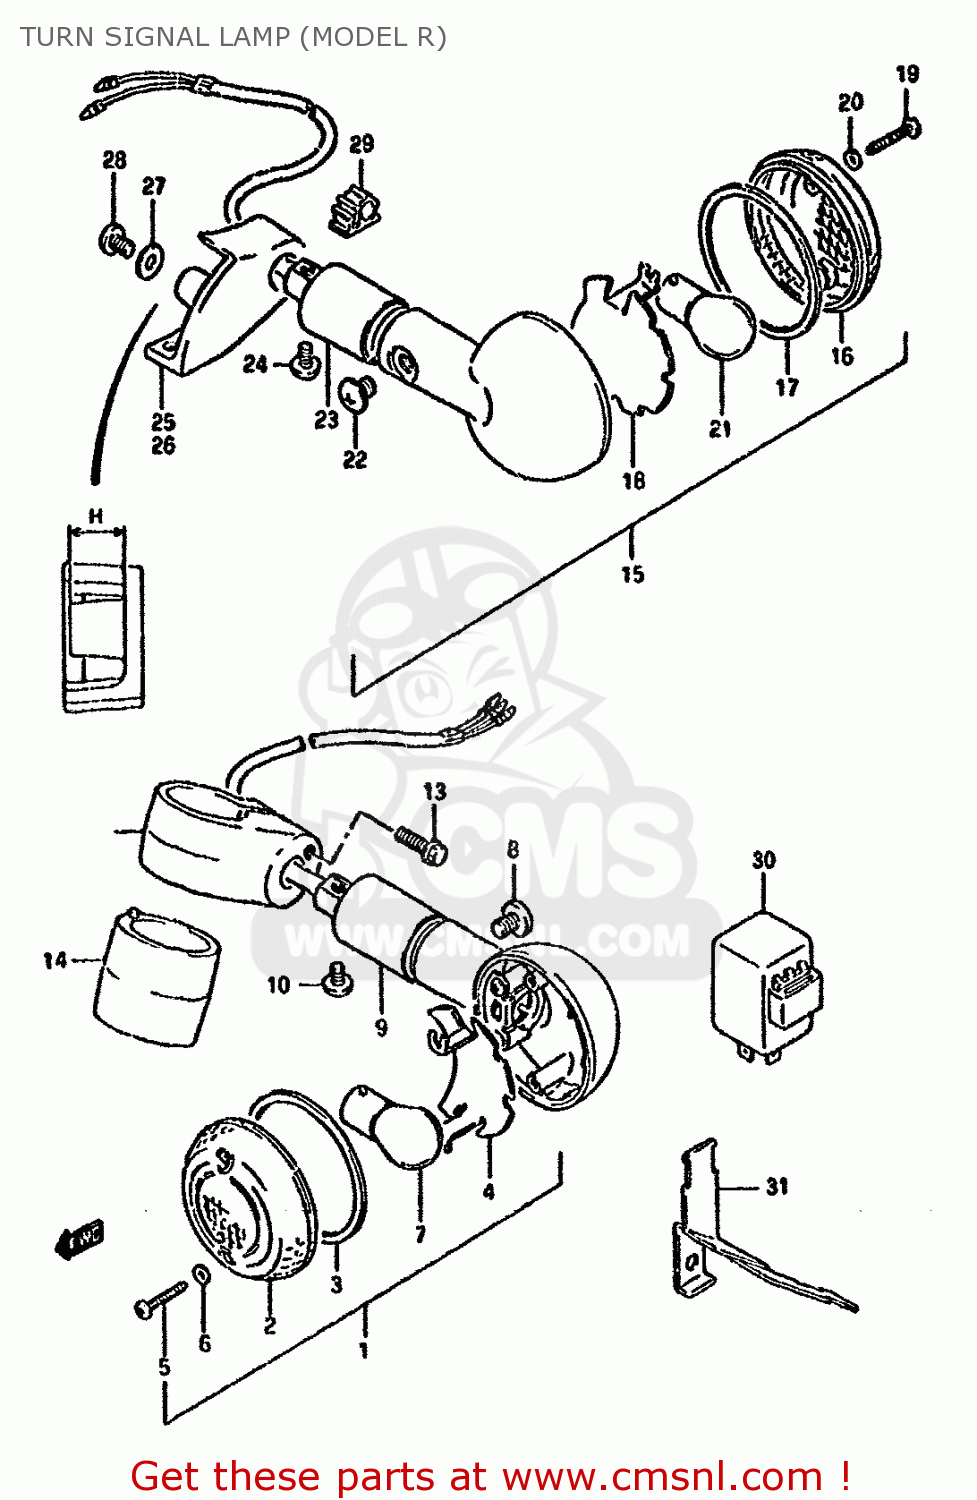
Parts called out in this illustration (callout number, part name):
1	LAMP ASSY,FR TURN SIGNAL
2	LENS
3	GASKET (NAS)
4	REFLECTOR
5	SCREW
6	GASKET (NAS)
7	BULB(12V21W)
8	SCREW
9	STAY,TURNSIGNAL LAMP
10	SCREW
11	BRACKET,FR TURNSIGNAL LAMP,R
12	BRACKET,FR TURNSIGNAL LAMP,L
13	BOLT
14	SPACER,FR TURNSIGNAL LAMP BRKT
15	LAMP ASSY,RR TURNSIGNAL,R
16	LENS
17	GASKET (NAS)
18	REFLECTOR
19	SCREW
20	GASKET (NAS)
21	BULB(12V21W)
22	SCREW
23	STAY,TURNSIGNAL LAMP
24	SCREW
25	BRACKET,REAR RH
25A	BRACKET,RR TURNSIGNAL,R
26	BRACKET,REAR LH
26A	BRACKET,RR TURNSIGNAL,L
27	WASHER
28	SCREW 6X12
29	CLAMP
30	RELAY ASSY,TUR
31	BRACKET,TURNSIGNAL RELAY
32	BRACKET,TURN SIGNAL RELAY
33	BRACKET,TURNSIGNAL RELAY
